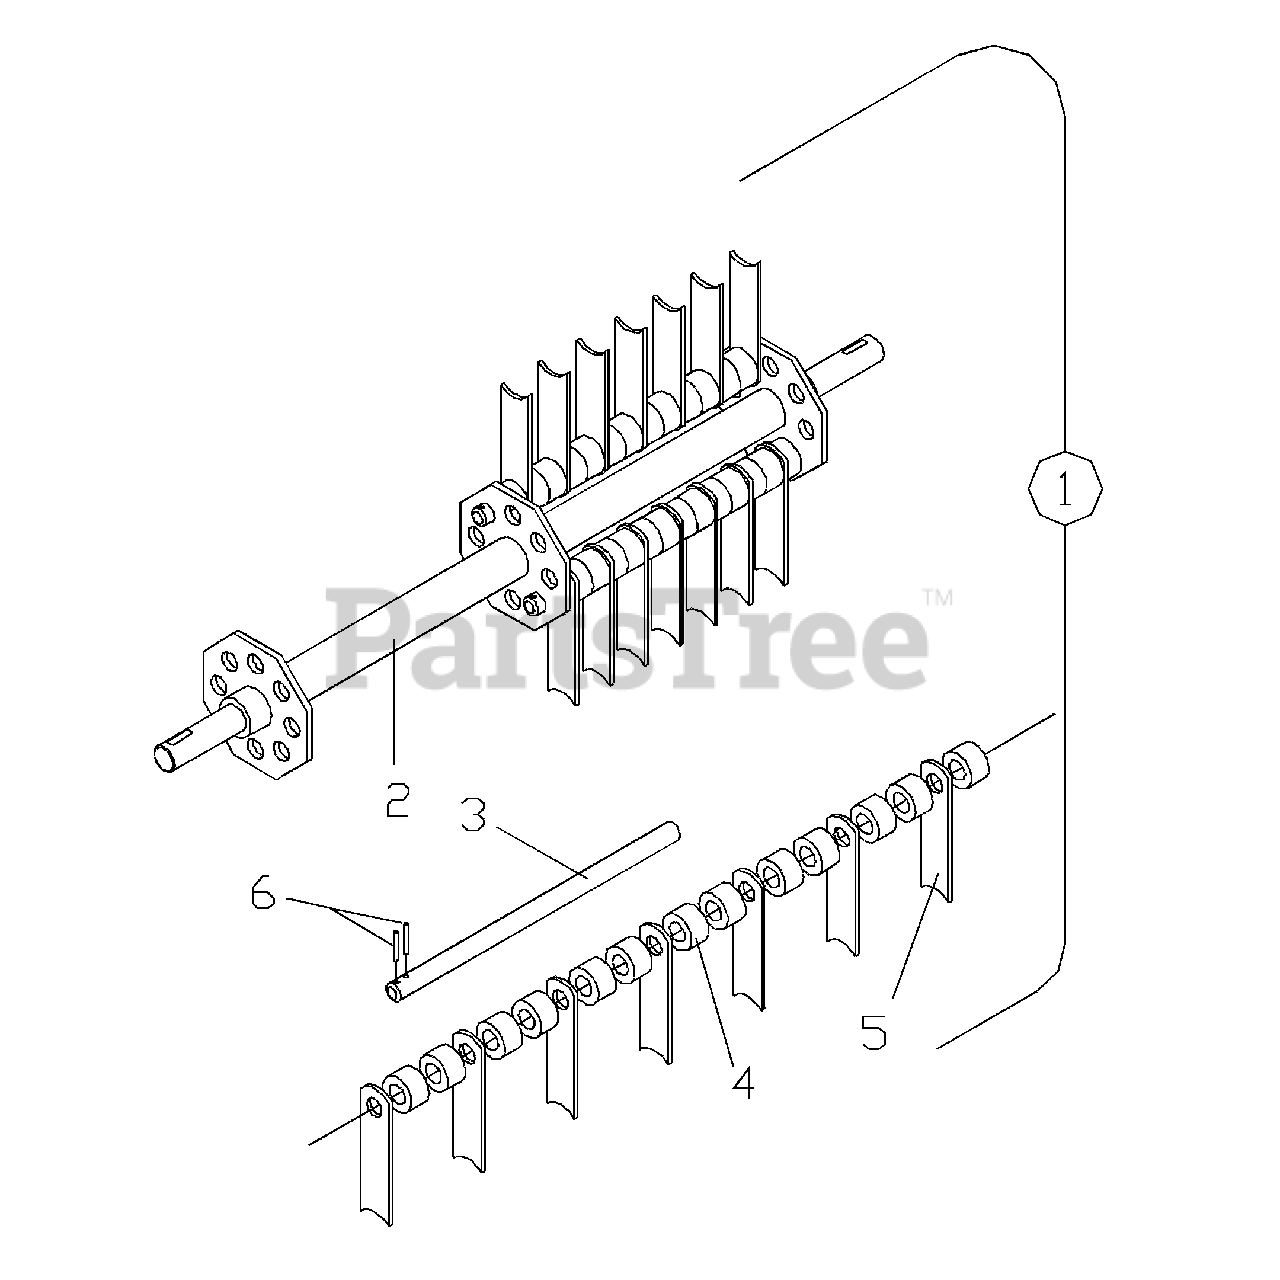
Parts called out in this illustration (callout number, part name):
1	DETHATCHER SHAFT, COMPLETE
2	DETHATCHER SHAFT
3	SATELLITE SHAFT
6	1/8 X 7/8 ROLL PIN
